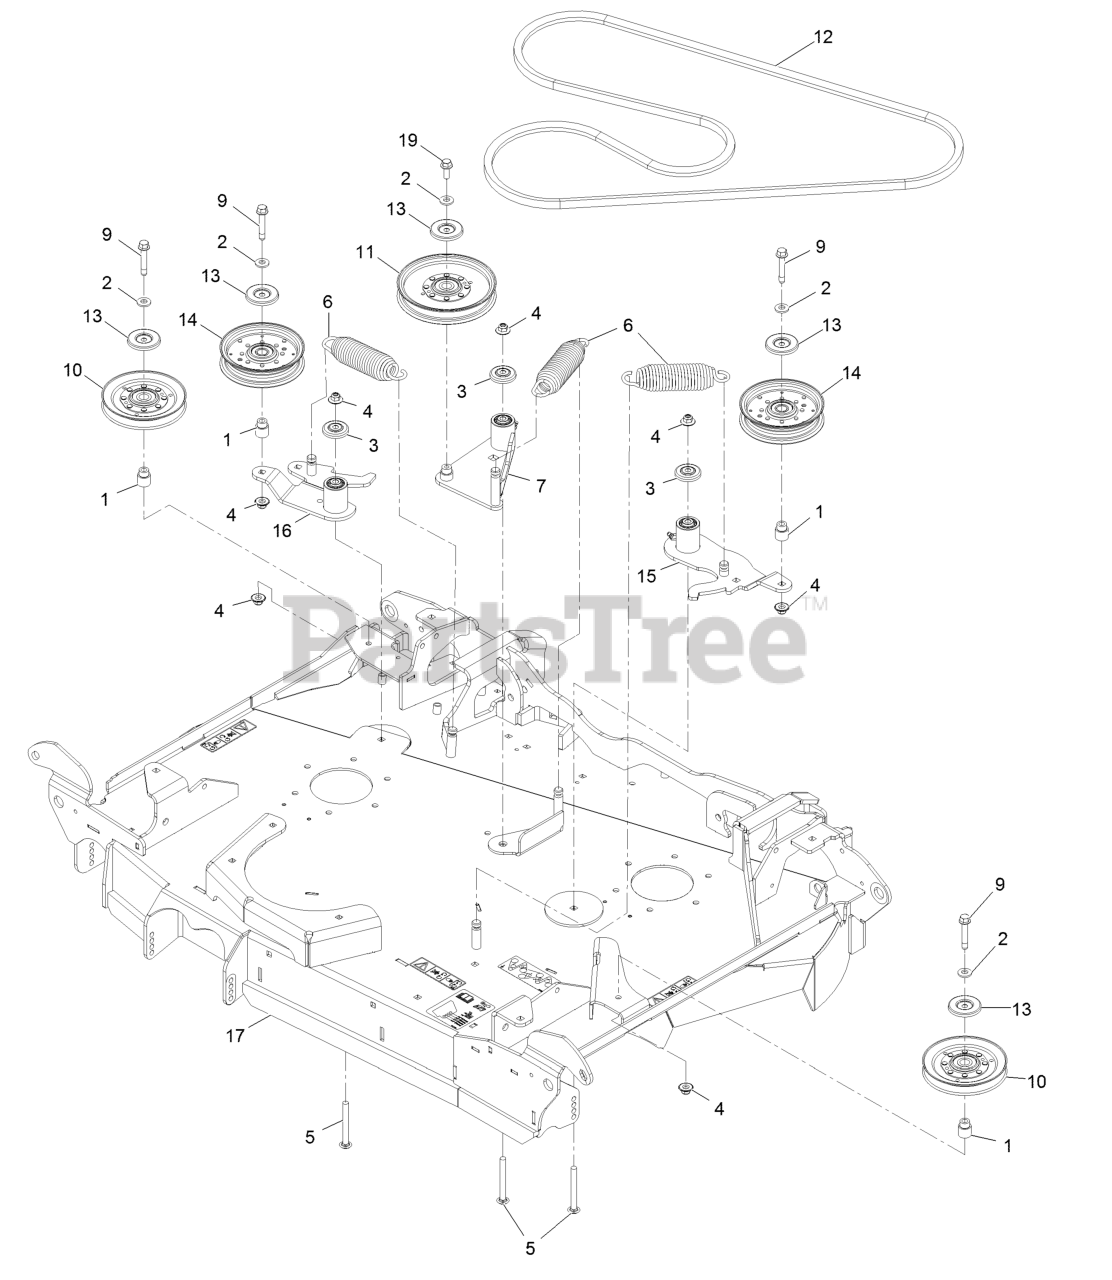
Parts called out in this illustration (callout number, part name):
1	Bushing, Idler
2	Washer-Spring Disc 3/8
3	Guard-Top
4	Nut-Nyloc 3/8-16 Flg
5	Bolt-Carriage Shoulder 3/8-16 X 3 1/2
6	Spring-Extension
7	Idler Arm ASM
9	Screw-HHF W/ Patch
10	Idler-V
11	Idler-Pulley
13	Shield-Dust
14	Pulley-Idler, Flat
15	Idler ASM
16	Idler ASM
17	ASM-Deck, Ctr 96/120
19	Screw HHF 3/8-16 X 1
